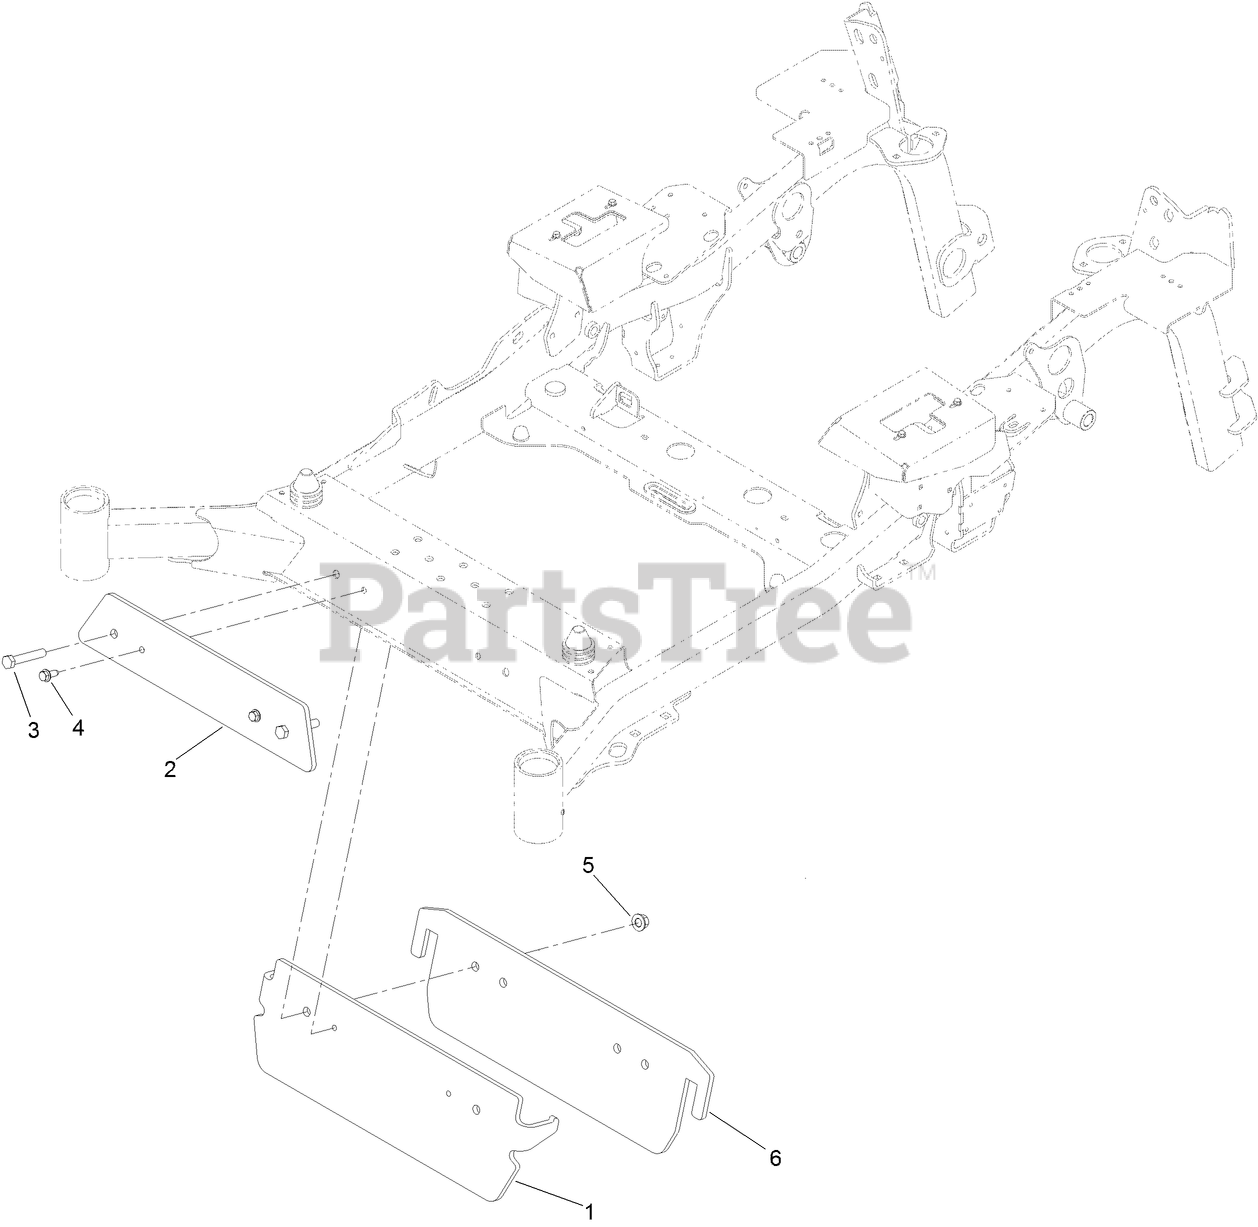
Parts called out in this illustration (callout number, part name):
1	BRACKET-WEIGHT
2	WEIGHT-OUTER
3	SCREW-HH, TAP
4	SCREW-FORMING, THREAD
5	NUT-LOCK
6	WEIGHT-INNER
